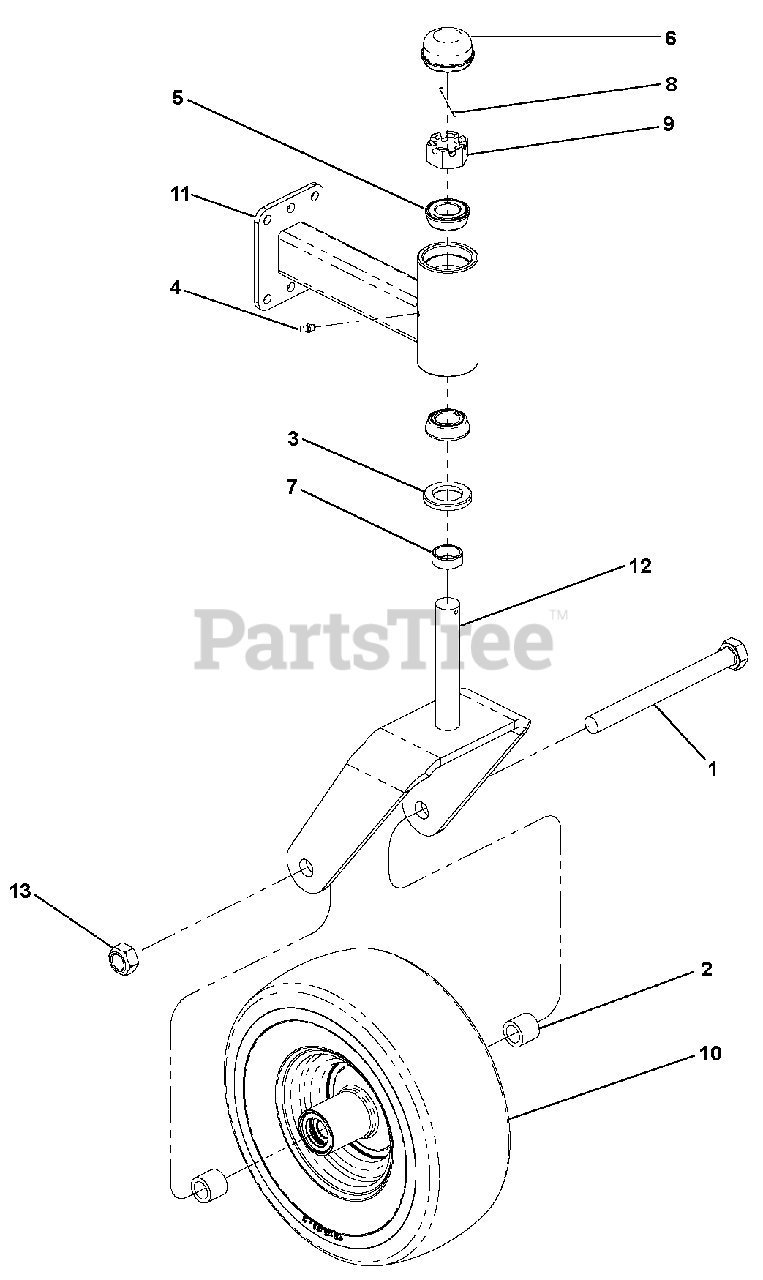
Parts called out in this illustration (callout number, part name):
1	Wheel Bolt, Caster
2	Spacer Assembly
3	Seal, Wheel Bearing
4	Fitting, Lubrication
5	Cone, Bearing
6	Cap, Dust
7	Spacer, Caster
8	Pin, Cotter, DIN94, 3.2 x 50-Steel-ZN
9	Nut, Hex Slot 1.00
10	Assembly, Caster Wheels and Tire
11	Weldment, Front Caster Support S/O
12	Weldment, Yoke
13	Locknut, 3/4 - 16 Crown
